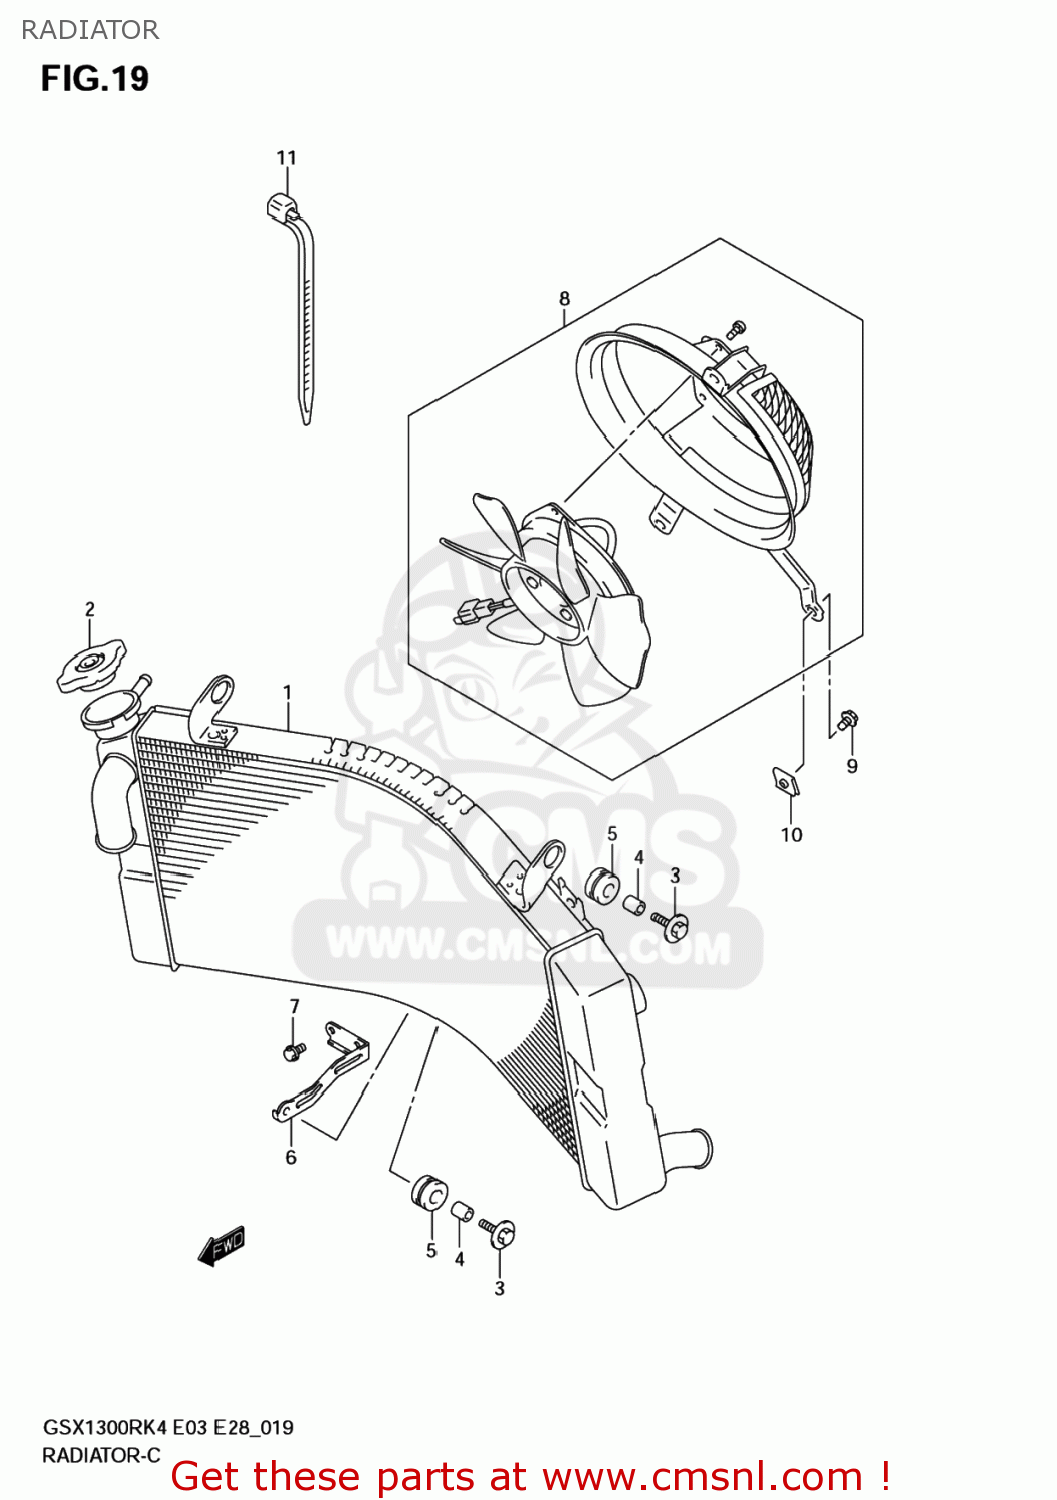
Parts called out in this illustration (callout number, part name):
1	RADIATOR ASSY,WATER
2	CAP COMP,RADIATOR
3	BOLT(6X25)
4	SPACER(6.5X10X12)
5	CUSHION
6	BRACKET,RADIATOR
7	BOLT
8	FAN ASSY,RADIATOR
9	BOLT
10	NUT
11	CLAMP(L:165)
